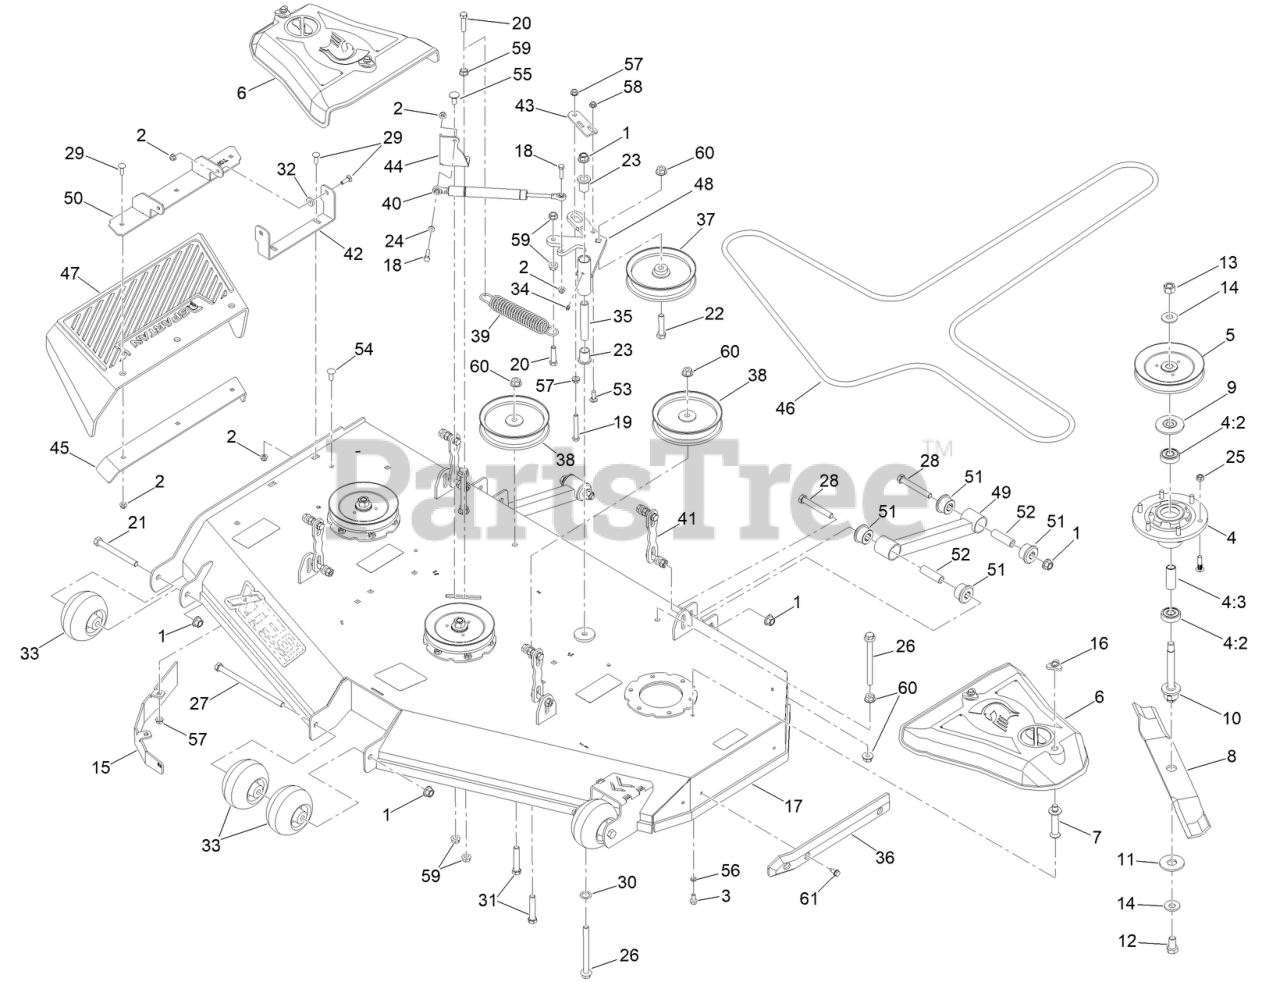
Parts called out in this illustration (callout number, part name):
1	NUT-LOCK
2	NUT-HF, NI
3	SCREW-HHF
4	SPINDLE ASM 5IN DECK
4:2	BEARING
4:3	SPACER, BEARING
5	PULLEY
6	COVER-BELT
7	PIN-BELT COVER
8	BLADE-ROTARY
9	GUARD-BEARING TOP 0.673IN
10	SHAFT - SPINDLE
11	WASHER-HEX
12	M16X1.5-30MM C10.9 HEX BOLT
13	M16X1.5 C8.8 HEX NUT
14	M16 SPRING WASHER (39MMOD/ 3.9MM THK)
15	BAFFLE-WIPER
16	NUT-KNOB
17	ASM-DECK W/ DECALS
18	SCREW-HH
19	SCREW-HH
20	SCREW-HH
21	SCREW-HH
22	SCREW-HH
23	3/4IN ID X15/16IN OD X 1-1/8IN FLNG BUSH
24	.312IDX.625ODX.062 THK THRUST BRG OI BRZ
26	1/2-13 X 5-1/2 HEX FLANGE BOLT GR 8 ZY
27	1/2-13 X 8-1/2 HEX C/S GR 2 ZINC YELLOW
28	1/2-13 X 3-3/4 HEX C/S (GR.5) ZC/YEL
29	5/16-18 X 1 CARRIAGE BOLT GR 8 YZ
30	.767IDX1.125ODX.016 THK TRIP WV WASHER
31	1/2-13 X 2-3/4 HEX FLANGE BOLT (GR.8) YZ
32	.312 ID X .875OD X .1875 THK F/W NYL
33	MWR ANTI-SCALP WHL W/O GREASE FITTING
34	1/4IN DRIVE TYPE GREASE FITTING YZ
35	MWR INNER IDLER SPACER
36	MWR NYLON DECK GUARD
37	6-3/4IN IDLER PULLEY 7/16IN SPACER ASM
38	6-3/4IN IDLER PULLEY 15/16IN SPACER ASSY
39	MWR DECK SPRING
40	IDLER GAS SPRING
41	RZ MWR DECK LINK ASM
42	MWR CHUTE MTG BRKT PAINTED
43	DECK IDLER PULLEY BELT RETNR BRKT PAINT
44	DECK BELT IDLER DAMPER MTG BRKT PAINTED
45	RZ MWR DECK CHUTE HNGE BACKR BRKT PAINT
46	61 DECK BELT
47	RZ MWR RUBBER DISCHARGE CHUTE
48	MWR DECK IDLER PULLEY ARM ASSY PAINT
49	RZ MWR DECK STABILIZER ASSY PAINTED
50	2020 RZ MWR DECK CHUTE HINGE ASSY PAINT
51	RED A80 SUSP BUSHING
52	UTV A-ARM BUSHING SLEEVE
53	BOLT-CARR
54	SCREW-CARR
55	SCREW-CARR
56	WASHER-LOCK
57	NUT-HHF, WHIZ
58	NUT-HF
59	NUT-HF
60	NUT-HHF
61	SCREW-HWH, THREAD CUT
